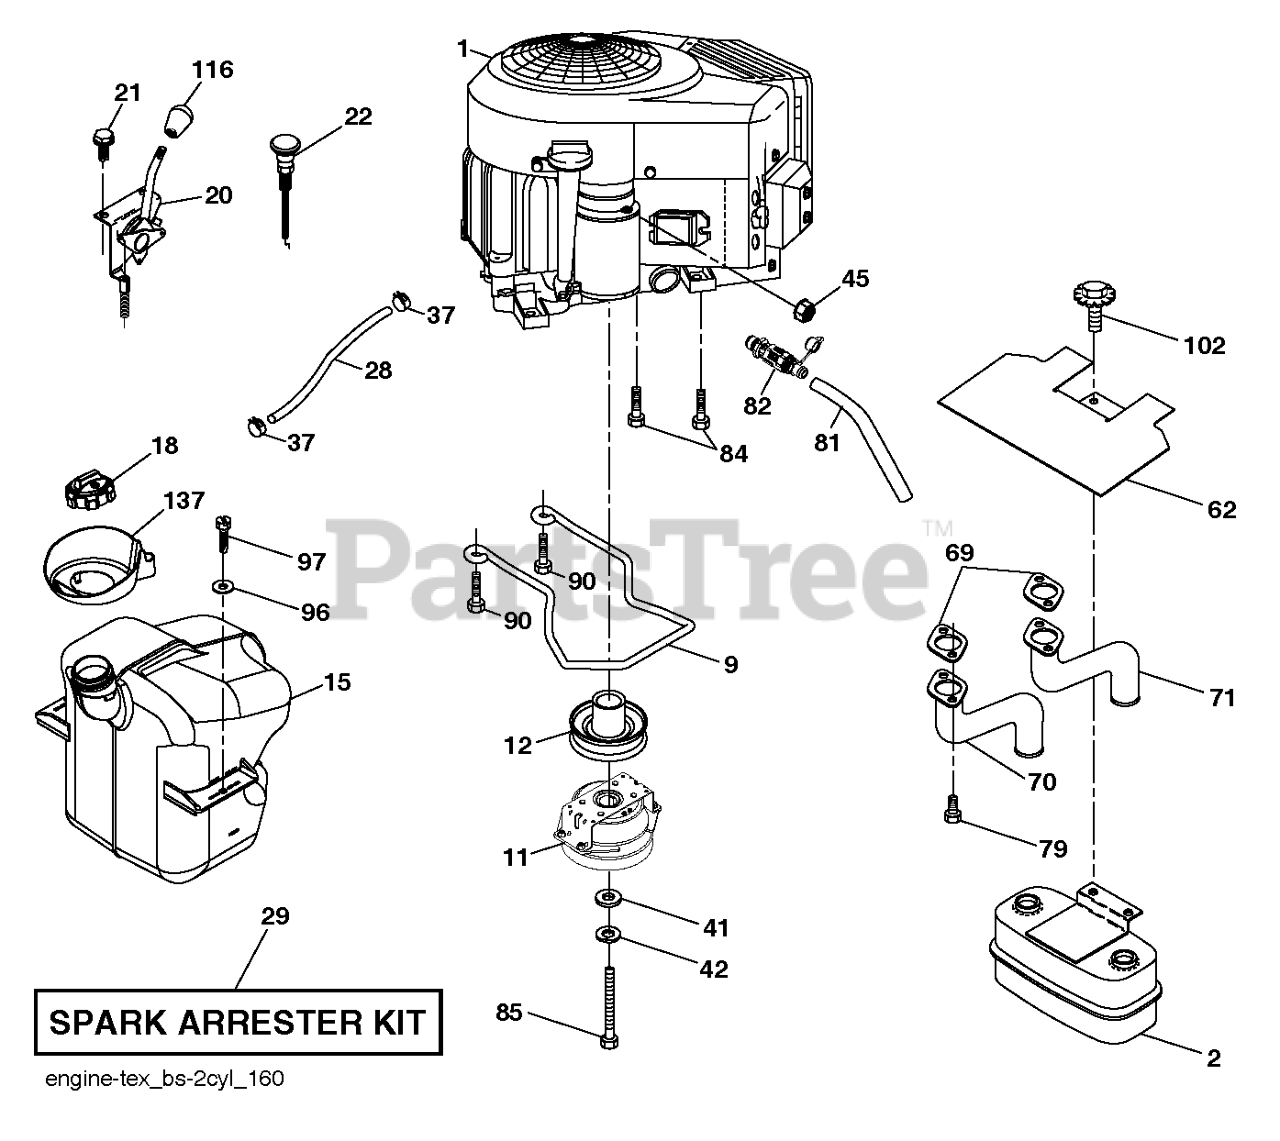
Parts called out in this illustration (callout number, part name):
2	MUFFLER.ASM.TWN.EXTNDED.DFLCTR
9	KEEPER.BELT.ENG.4.25"2.BLT.431
11	CLUTCH.OGURA.5.0PD.GT1.5A-EH07
12	PULLEY.ENGINE.TUFFTORQ
15	FUEL TANK TANK. ASSEMBLY. EXTE
18	CAP.ASM.FUEL.2.25"TOP.TURN
20	CONTROL.THROTTLE.PRO.
21	SCREW.#10 X 0.750.BOS
22	CONTROL, CHOKE
28	LINE.FUEL.20
29	KIT.SPARK ARRESTOR 794945 B&S
37	HOSE CLAMP
42	LOCKWASHER
45	NUT
62	SHIELD.HEAT.MUFFLER
69	GASKET.MUFF 806237 NOW 806425
70	EXHAUST.TUBE.MUFFLR.LH.VANG
71	EXHAUST.TUBE.MUFFLR.RH.VANG
79	SCREW.TUBE.MUFFLER.VANGUARD
81	TUBE, DRAIN OIL ASM.
82	VALUE.OIL.DRAIN
84	SCREW.3/8-16
85	BOLT.HEX.7/16-20X3.75.GR5.RED
90	SCREW 3/8-16X1
96	WASHER
97	SCREW HEXWSHR 1/4-20X3/4
102	SCREW
116	KNOB - SHIFT
